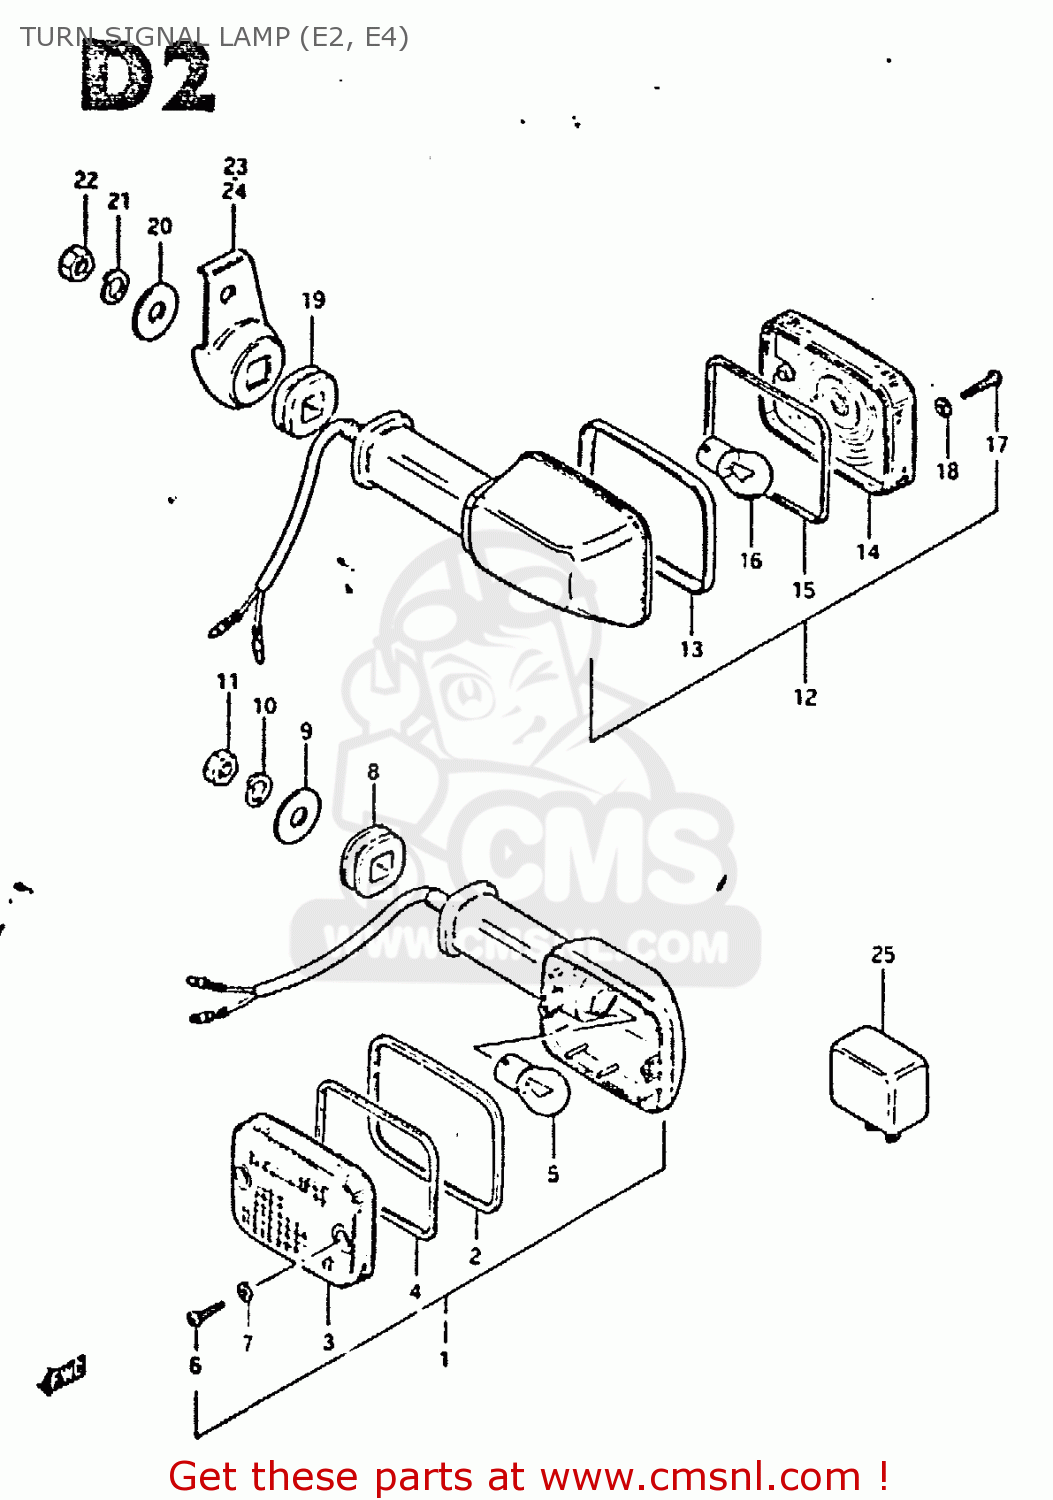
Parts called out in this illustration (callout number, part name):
1	LAMP ASSY,FR T
2	RIM
3	LENS
4	GASKET (NAS)
5	BULB(12V21W)
6	SCREW
7	GASKET (NAS)
8	CUSHION
9	WASHER (10.5X30X2.3)
10	LOCK WASHER
11	NUT
12	LAMP, REAR TURN SIGNAL
13	RIM
14	LENS
15	GASKET (NAS)
16	BULB(12V21W)
17	SCREW
18	GASKET (NAS)
19	CUSHION
20	WASHER (10.5X30X2.3)
21	LOCK WASHER
22	NUT
23	BRACKET,REAR TURN SIGNAL
24	BRACKET,REAR TURN SIGNAL
25	RELAY ASSEMBLY,TURN SIGNAL
